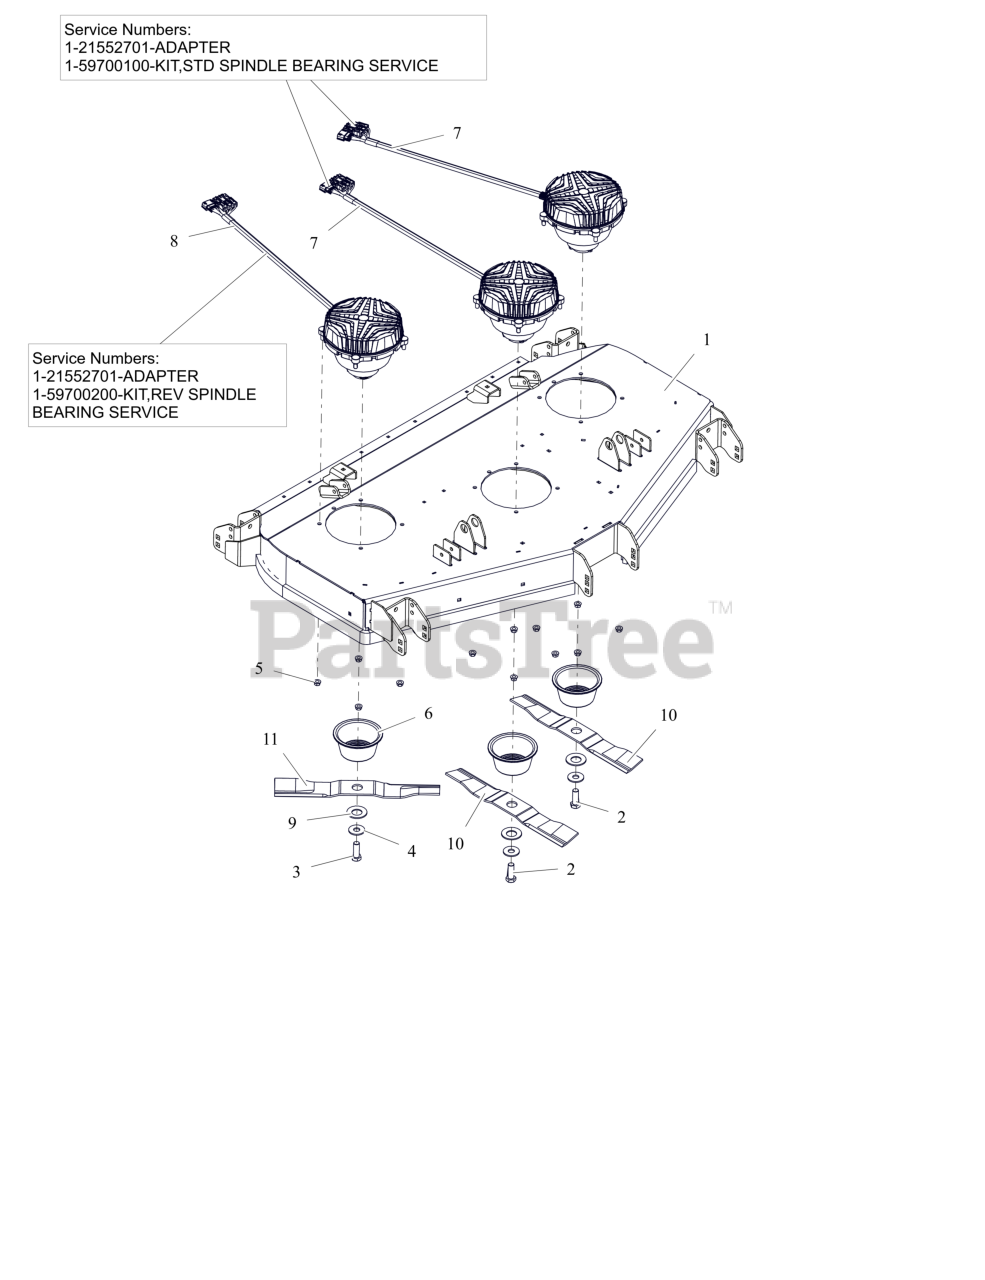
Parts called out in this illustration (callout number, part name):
1	KIT,DECK 52 RD W/DECALS-G
2	BLT, HEX .62-18X1.75 G8 ZCC
3	BLT, HEX 0.625-11X1.75 GR8 ZCC LH
4	WSHR, HRDN 0.687X1.75X0.134 HRD
5	NUT-LK-CTR-FLG .375-16 GF ZCC
6	GUARD, SPINDLE LOWER
7	MOTOR, DECK - 48"/52" CW
7	ADAPTER
7	KIT, STD SPINDLE BEARING SERVICE
8	MOTOR, DECK - 48"/52" CCW
8	ADAPTER
8	KIT,REV SPINDLE BEARING SERVICE
9	WSHR, BLVL - .56X28.5X3 PHOS.COAT
10	BLADE, MOWER - 18.00" EFF CW
11	BLADE, MOWER -18.00" EFF CCW
